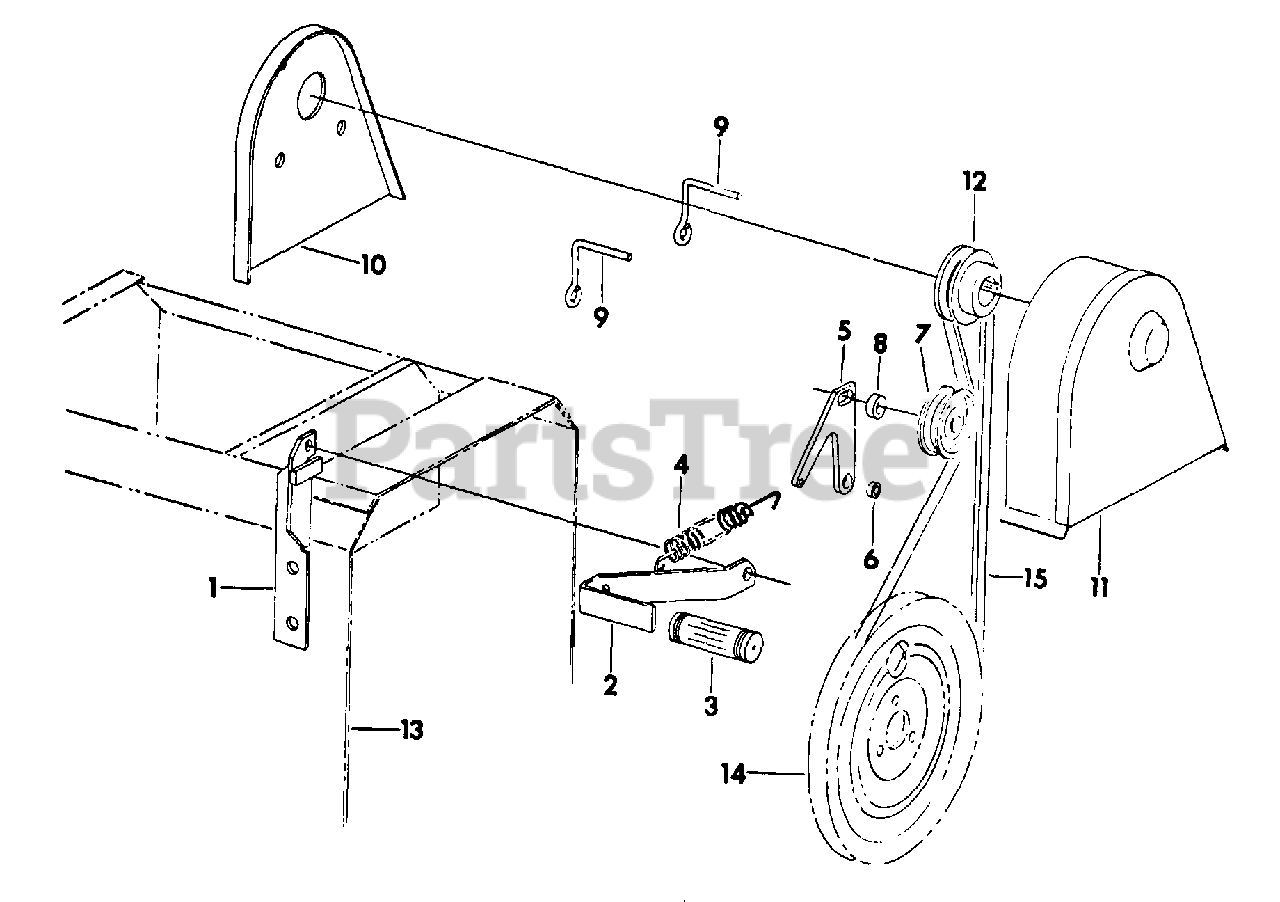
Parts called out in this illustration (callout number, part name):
1	BRACKET, BELT CONTROL
2	LEVER, BELT CONTROL
3	GRIP, RUBBER HANDLE
4	SPRING, BELT TENSION
5	BRACKET, IDLER
7	PULLEY, IDLER
8	SPACER, IDLER MOUNTING
10	PLATE, BELT GUARD BACK
11	PLATE, BELT GUARD FRONT
12	SHEAVE, ENGINE DRIVE
13	HOUSING, WELDED
14	SHEAVE
15	BELT, DRIVE
